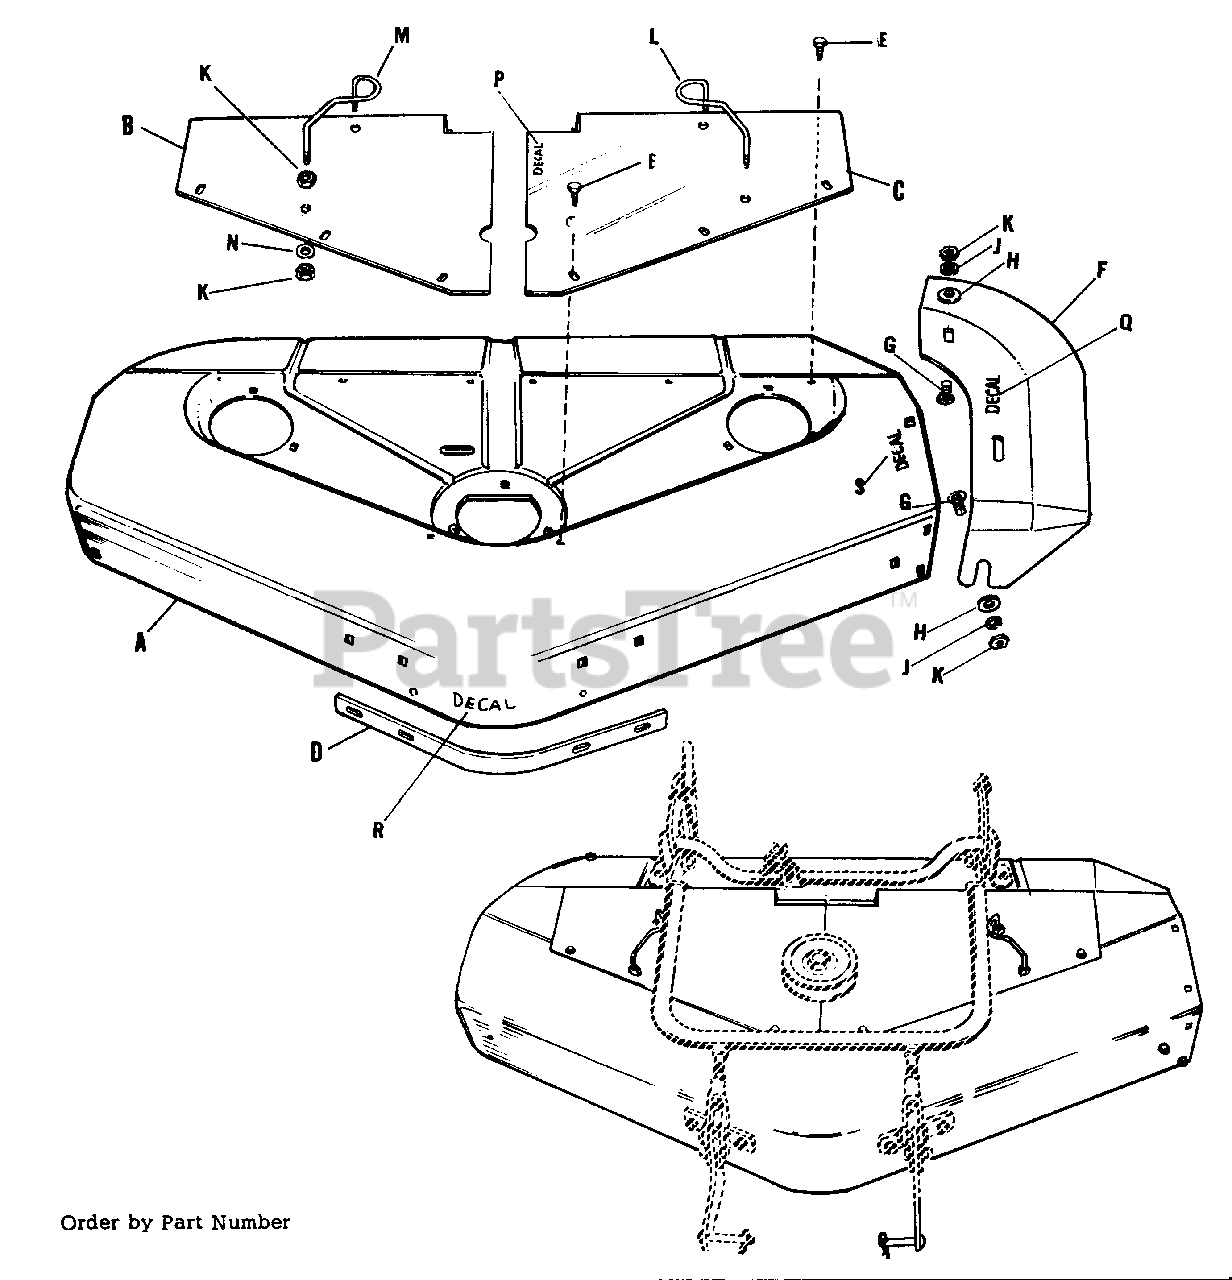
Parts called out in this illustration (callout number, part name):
A	Mower Housing
B	Cover, R.H.
C	Cover, L.H.
D	Bar, Reinforcing
E	Screw, Taptite, 1/4-20 x 3/8" lg.
F	Deflector
G	Bolt, 3/8-16 x 3/4 lg.
H	Spacer
J	Washer, Lock, 3/8"
K	Hex Nut, Full, 3/8-16
L	Guard, L.H.
M	Guard, R.H.
N	Washer, Plain, 3/8
